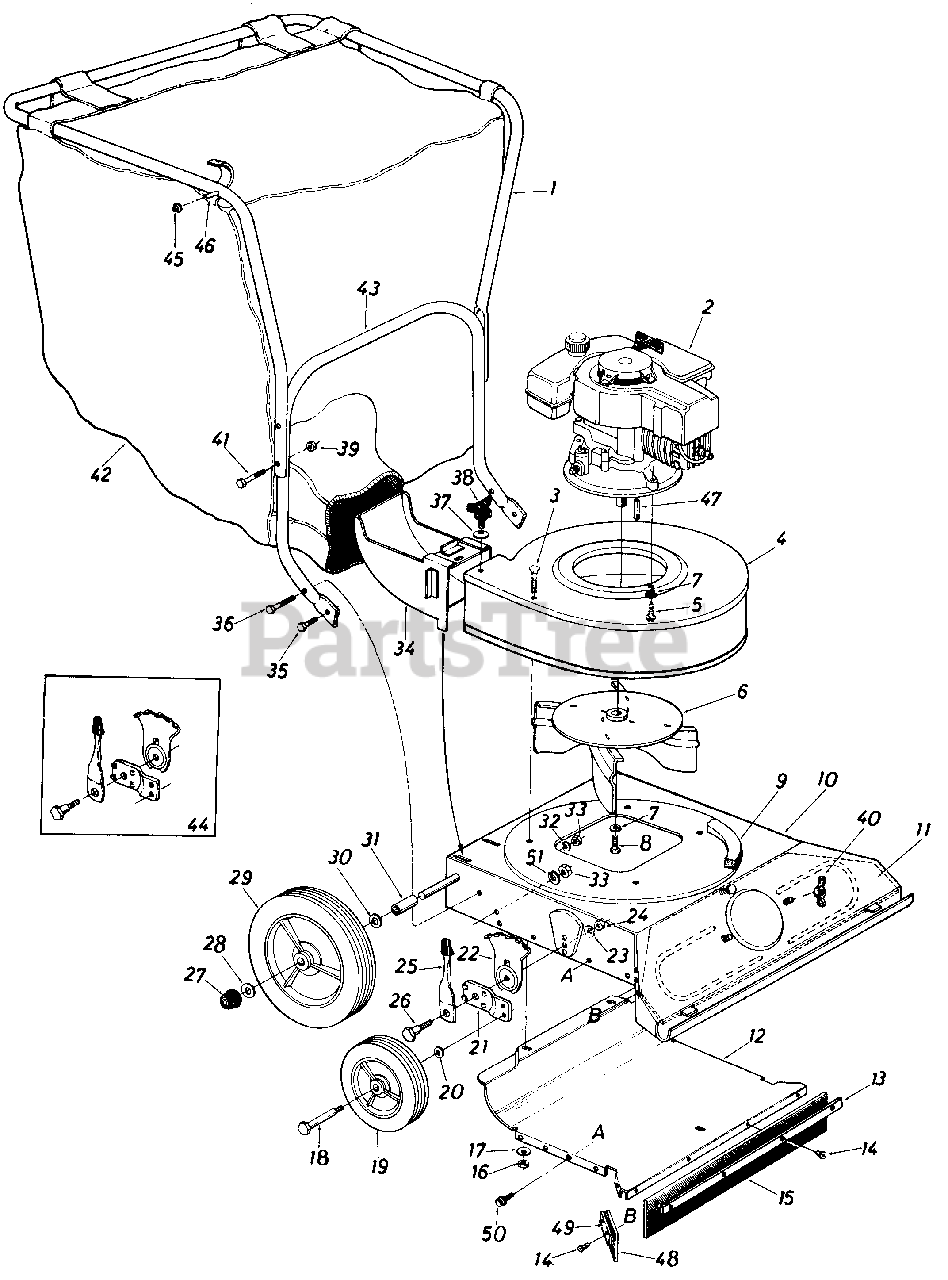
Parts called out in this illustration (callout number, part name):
1	Upper Handle (Painted)
2	Engine
3	Carriage Bolt 5/16-18 x .62" Lg.*
4	Blower Housing Ass'y.
5	Hex Tap Scr. 3/8-16 x 1.00" Lg.
6	Impeller Ass'y.
7	L.-Wash. 3/8" I.D.*
8	Hex Bolt 3/8-24 x 1.0" Lg. w/Patch
9	P.V.C. Foam Strip (4-Pcs. 12" Lg.)
10	Vacuum Deck Ass'y.
11	Front Baffle Ass'y.
12	Lower Baffle Ass'y.
13	Wiper RetainingStrip
14	Pop Rivet.188" Dia.
15	Nozzle Wiper Rear
16	Hex Nut 5/16-18 Thd.*
17	Bell.-Wash. .34" I.D. x .87" O.D.
18	Shld. Bolt 1/2" Dia. x 1.45" Lg. (3/8-16)
19	Wheel Ass'y. Comp. 8 x 1.75" - Front
20	Bell.-Wash. .39" I.D. x 1.12" O.D.
21	Wheel Pivot Bar
22	Index Plate
23	Bell.-Wash. .39" I.D. x 1.12" O.D.
24	Hex Nut 3/8-16 Thd.*
25	Spring Lever Ass'y. w/Knob
26	Shoulder Bolt .500" x 7/16" Lg. (3/8-16)
27	Push Cap .50" Rod (Black)
28	Fl.-Wash. 1/2" I.D. x 1.0" O.D. x .06
29	Wheel Ass'y. Comp. 10 x 1.75" - Rear
30	Fl.-Wash. 1/2" I.D. x 1.0" O.D. x .06
31	Wheel Spacer 1/2" I.D. x 15/16" Lg.
32	Bell.-Wash. .39" I.D. x 1.12" 0.D.
33	Hex Nut 3/8-16 Thd.*
34	Air Duct Ass'y.
35	Hex Bolt 3/8-16 x .75" Lg.*
36	Hex Bolt 3/8-16 x 1.50" Lg.*
37	Bell.-Wash. .34" I.D. x.87" O.D.
38	Thumb Scr. 5/16-18 x .75" Lg.
39	Hex Cent. L.-Nut 1/4-2 Thd.
40	Wing Nut 1/4-20 (Plastic)
41	Hex Bolt 1/4-20 x 1.75" Lg.*
42	Vacuum Bag (6.6 Bushel)
43	Lower Handle (Painted)
44	Height Adjuster Ass'y. Comp.- R.H.
45	Push Speed Nut .25" Dia.
46	Stud Pin .250" Dia. x 1.75" Lg.
47	Sq. Key 3/16 x 3/16 x 1.00"Lg.
48	Nozzle Wiper Side
49	Wiper Retaining Strip
50	Hex Wash. Hd. "F" TapScr. #10
51	L-Wash. 3/8" I.D.*
